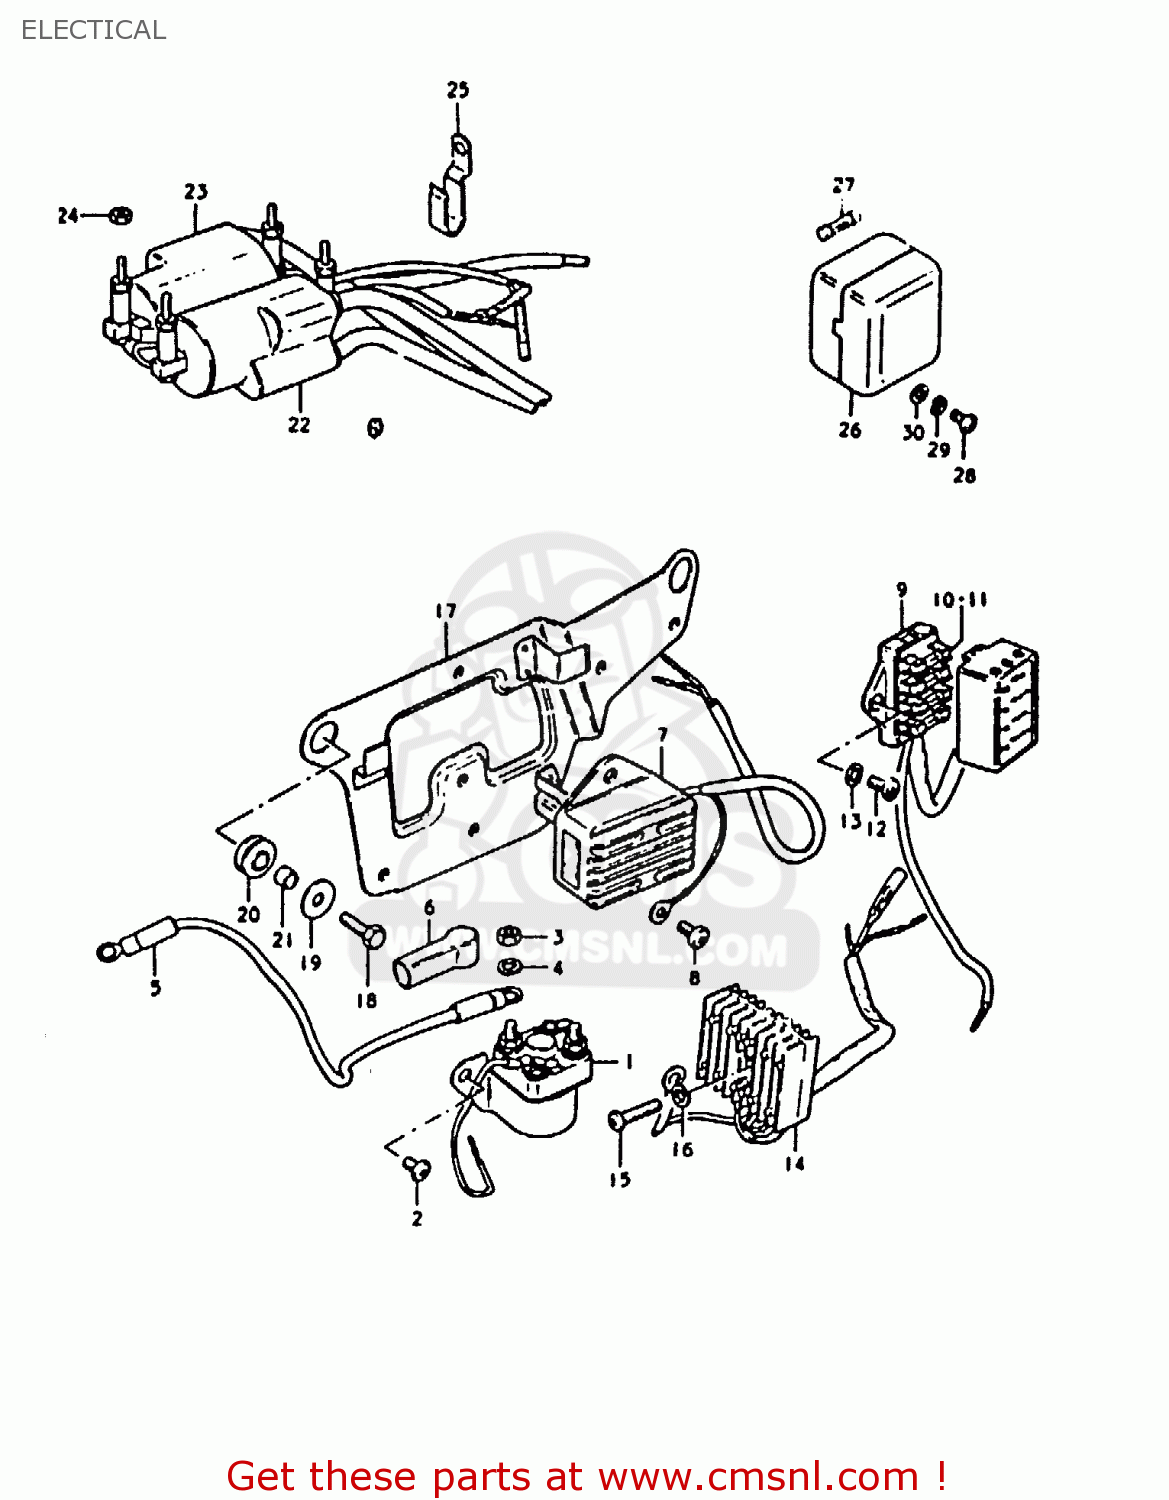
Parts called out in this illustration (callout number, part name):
1	RELAY ASSY,STARTING MOTOR
2	SCREW
3	NUT 6MM
4	LOCK WASHER
5	WIRE,STARTER MOTOR LEAD
6	CAP,STARTER RELAY
7	REGULATOR ASSY,VOLTAGE
8	SCREW
9	BOX ASSEMBLY,FUSE
10	FUSE(10A)
11	FUSE(15A)
12	SCREW 6X12
13	WASHER 6MM
14	RECTIFIER ASSEMBLY
15	SCREW
16	LOCK WASHER
17	HOLDER COMP,ELECTRONIC PARTS
18	BOLT, UPPER
19	WASHER(6,5X22X1.6)
20	CUSHION
21	SPACER(6.2X8.3X5.7)
22	COIL ASSEMBLY,IGNITION
23	COIL ASSEMBLY,IGNITION
24	NUT
25	CLAMP
26	TERMINAL ASSEMBLY,POWER SO
27	FUSE(10A)
28	SCREW
29	LOCK WASHER
30	WASHER
